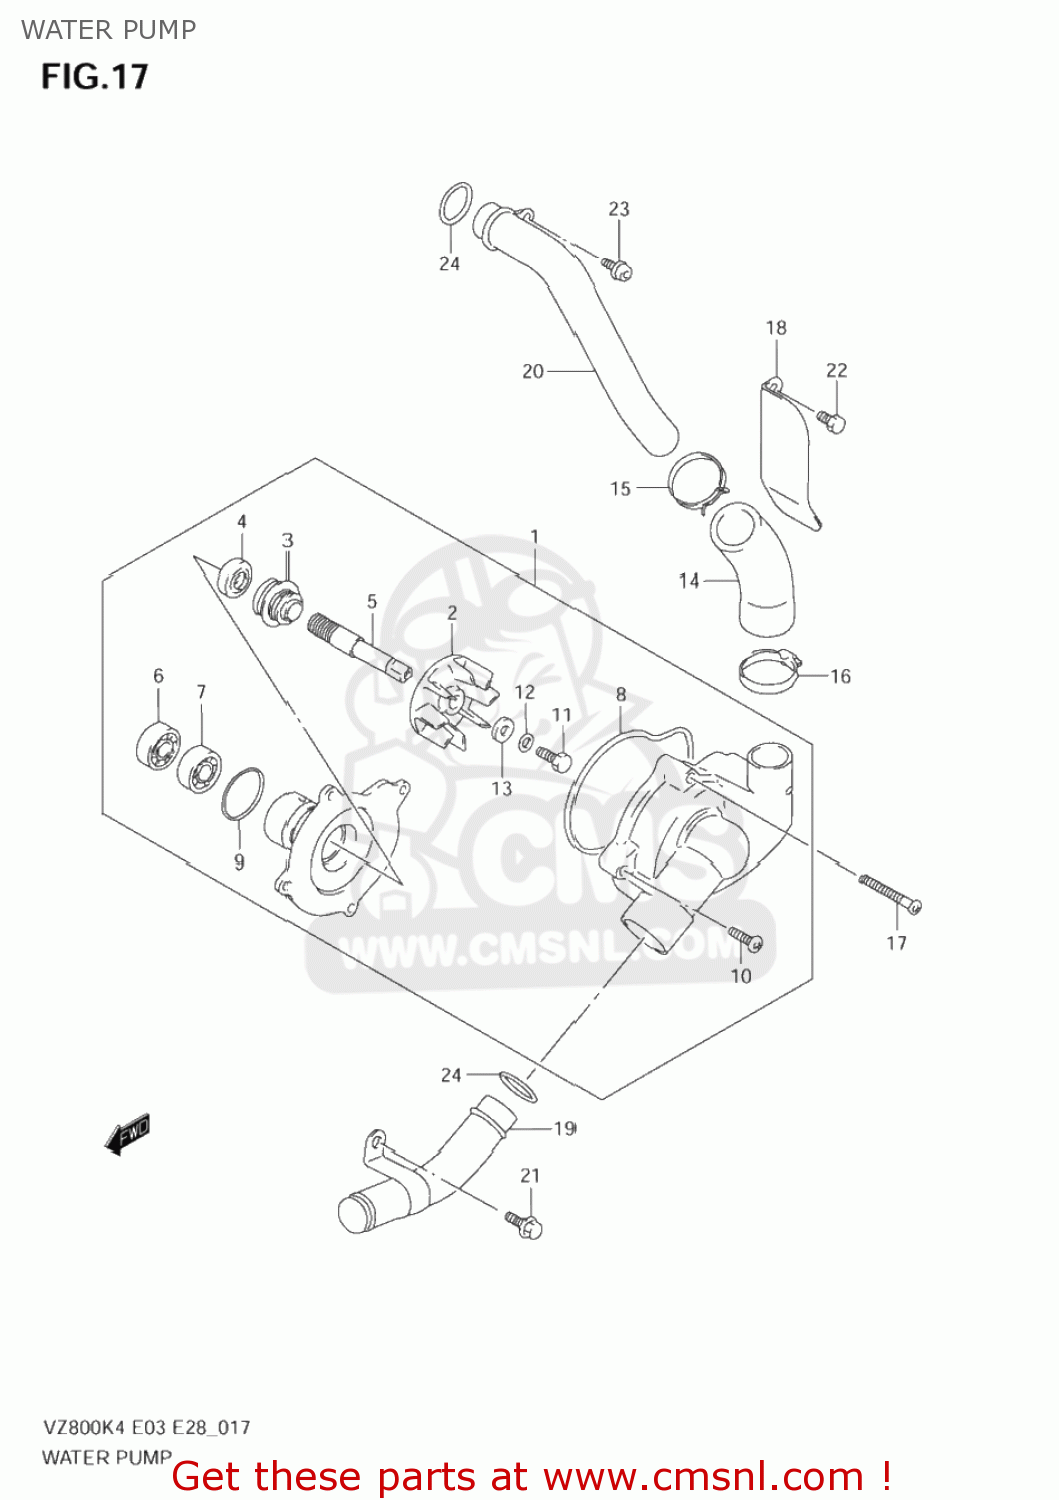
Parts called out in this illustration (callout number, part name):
1	PUMP ASSY,WATER
2	IMPELLER
3	SEAL,MECHANICAL
4	SEAL,OIL(10X21X5)
5	SHAFT,WATER PUMP
6	BEARING(10X26X8)
7	BEARING(12X28X8)
8	O RING
9	O RING,WATER PUMP HOLDER
10	SCREW 6X16
11	BOLT(6X13)
12	WASHER
13	GASKET(6X15X2.2) (NAS)
14	HOSE,WATER PUMP OUTLET
15	CLAMP
16	CLAMP
17	BOLT
18	PLATE,WATER HOSE
19	PIPE,WATER PUMP INLET
20	PIPE,WATER PUMP OUTLET
21	BOLT
22	BOLT
23	BOLT
24	O RING(D:2.7,ID:21.4)
